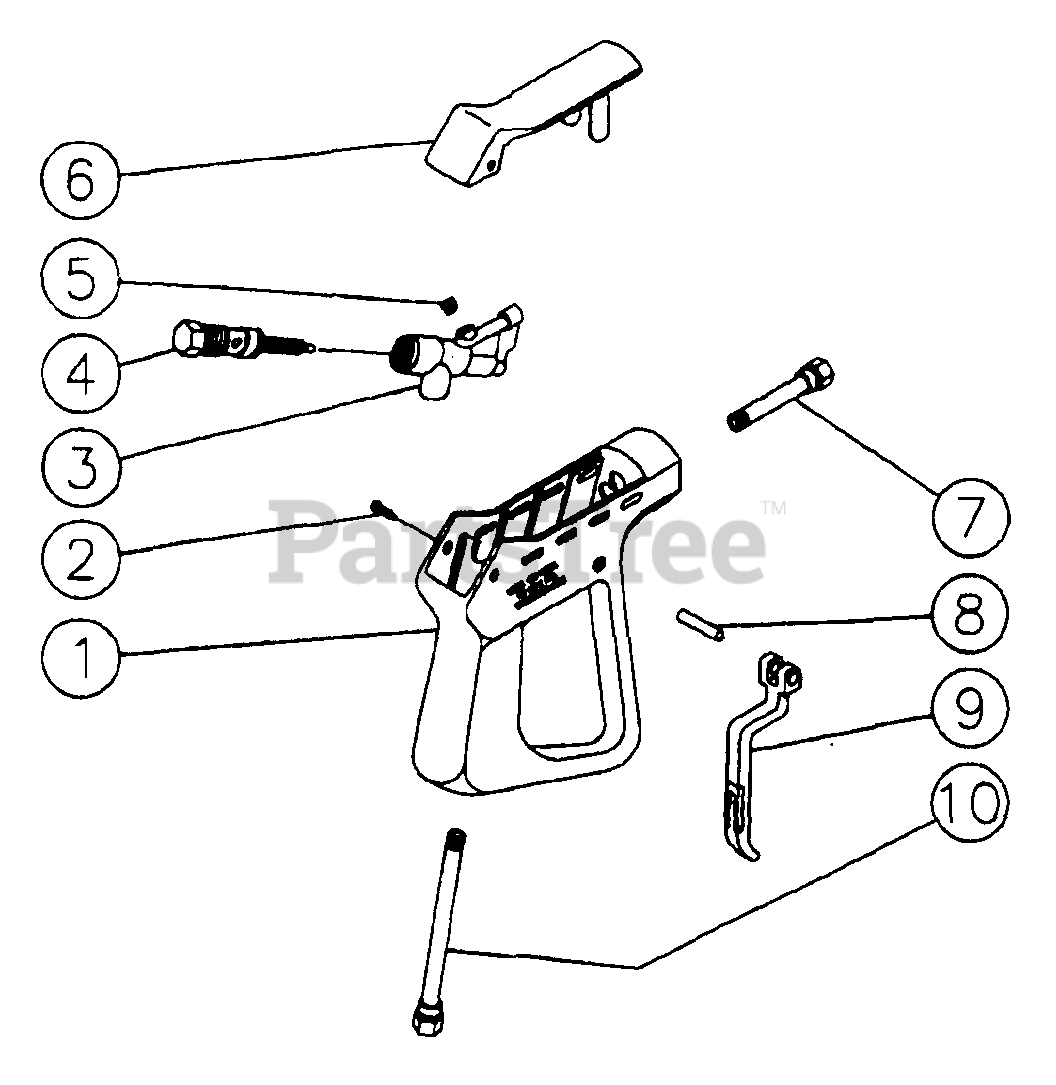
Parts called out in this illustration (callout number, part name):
1	Plastic Housing
3	Brass Housing
4	Gun Repair Kit
5	Brass Plug
6	Plastic Cover
7	Pipe Assembly
8	Trigger Pin
9	Trigger Safety Lock-off
10	Pipe Assembly-Inlet
